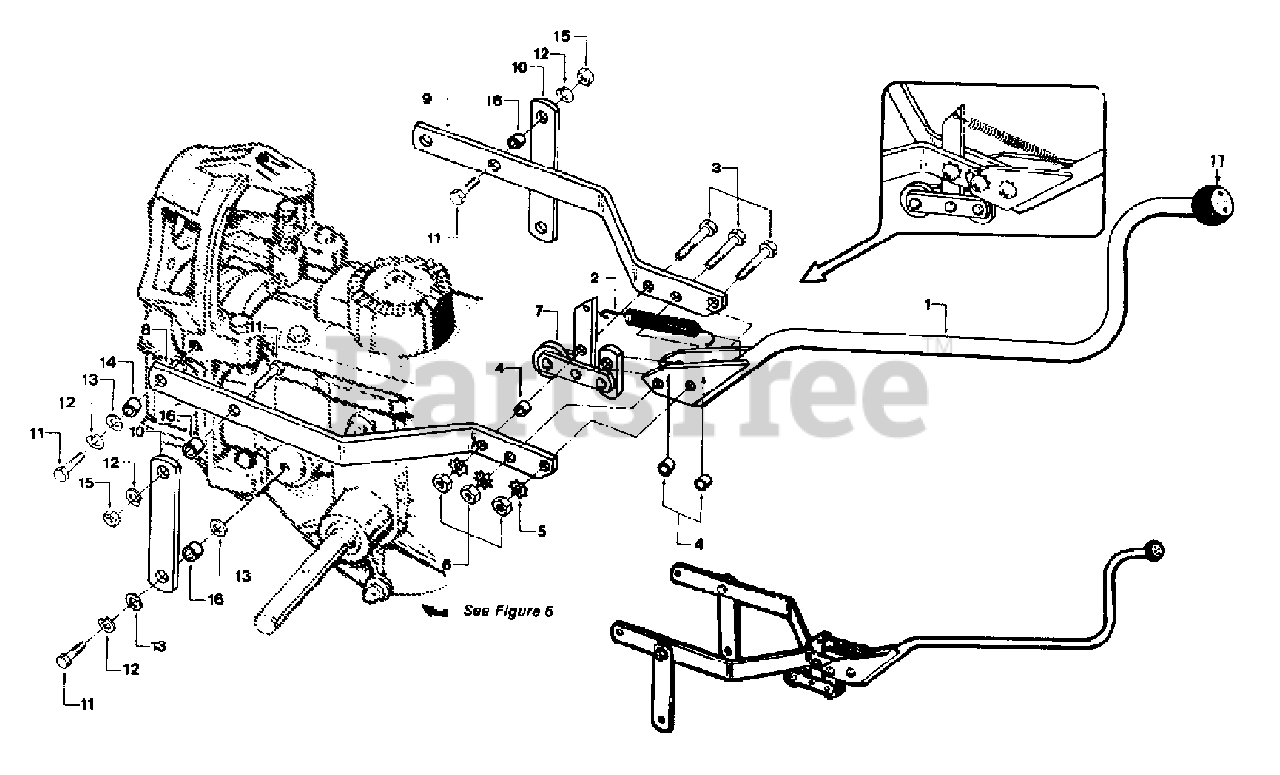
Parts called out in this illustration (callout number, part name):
1	LEVER - forward/neutral/reverse
2	SPRING - clutch pawl
3	BOLT - hex. hd., 5/16"-18 x 1-1/2"
4	BUSHING - 3/8" long
5	LOCKWASHER - external tooth, 5/16"
6	NUT - hex., 5/16"-18
7	ROLLER ASSEMBLY -forward/neutral/reverse shift lever
8	YOKE - left side
9	YOKE - right side
10	LINK- yoke pivot, left and right, & 7/8" long
11	BOLT - hex. hd., 3/8"-18 x 1"
12	LOCKWASHER - spring lock, 3/8"
13	WASHER - flat, 3/8", S.A.E
14	BUSHING - spacer, 21/64"/.325") long, yoke to engine mount
15	NUT - hex., 3/8"-16
16	BUSHING - spacer, 19/64" (.300") long, yoke link
17	KNOB -
